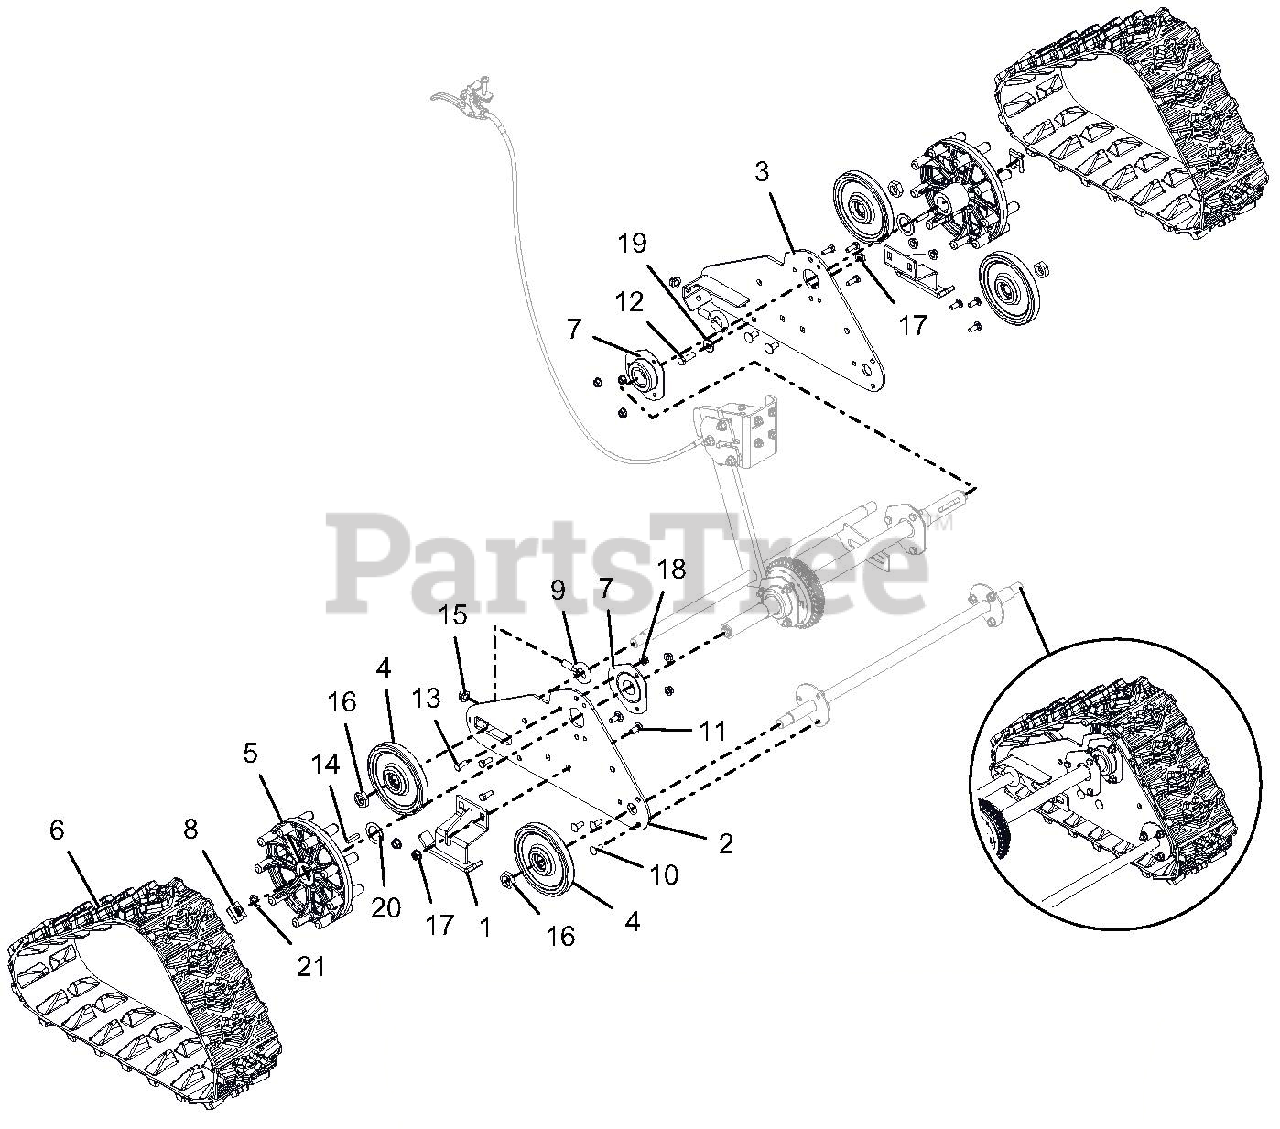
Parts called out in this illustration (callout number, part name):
1	RUNNER, GUIDE-TRACK
2	SIDE PLATE, RH-TRACK
3	SIDE PLATE, LH-TRACK
4	WHEEL, BOGIE - SINGLE BEARING
5	WHEEL, MACHINED DRIVE
6	TRACK, RUBBER
7	BRG-FLG 1.003/1.000 3 BOLT
8	CLIP, SNAP .625 DIA
9	BLT-EYE .375-16X.880 YWZC
10	@BLT-RDHDSQNK .25-20X.75 G5YZ
11	@BLT-RDHDSQNK .31-18X.75 G5YZ
12	@BLT-HEX .25-20X.75 GR5 YWZC
13	@BLT-HEX .25-20X.75 GR5 YWZC
14	KEY-RECT .25X.188X1.00
15	@NUT-LK-CTR-FLG .25-20 YWZC
16	@NUT-LK-NYL .625-18 YWZC
17	@NUT-LK-TOP-FLG .31-18 YWZC
18	@NUT-LK-TOP-FLG .25-20 YWZC
19	BSHG-FLG .325X.499X.3X.875
20	WSHR-FL-STL 1.010X1.505X.062YZ
21	RG-RTNG-EXT .625X.042
